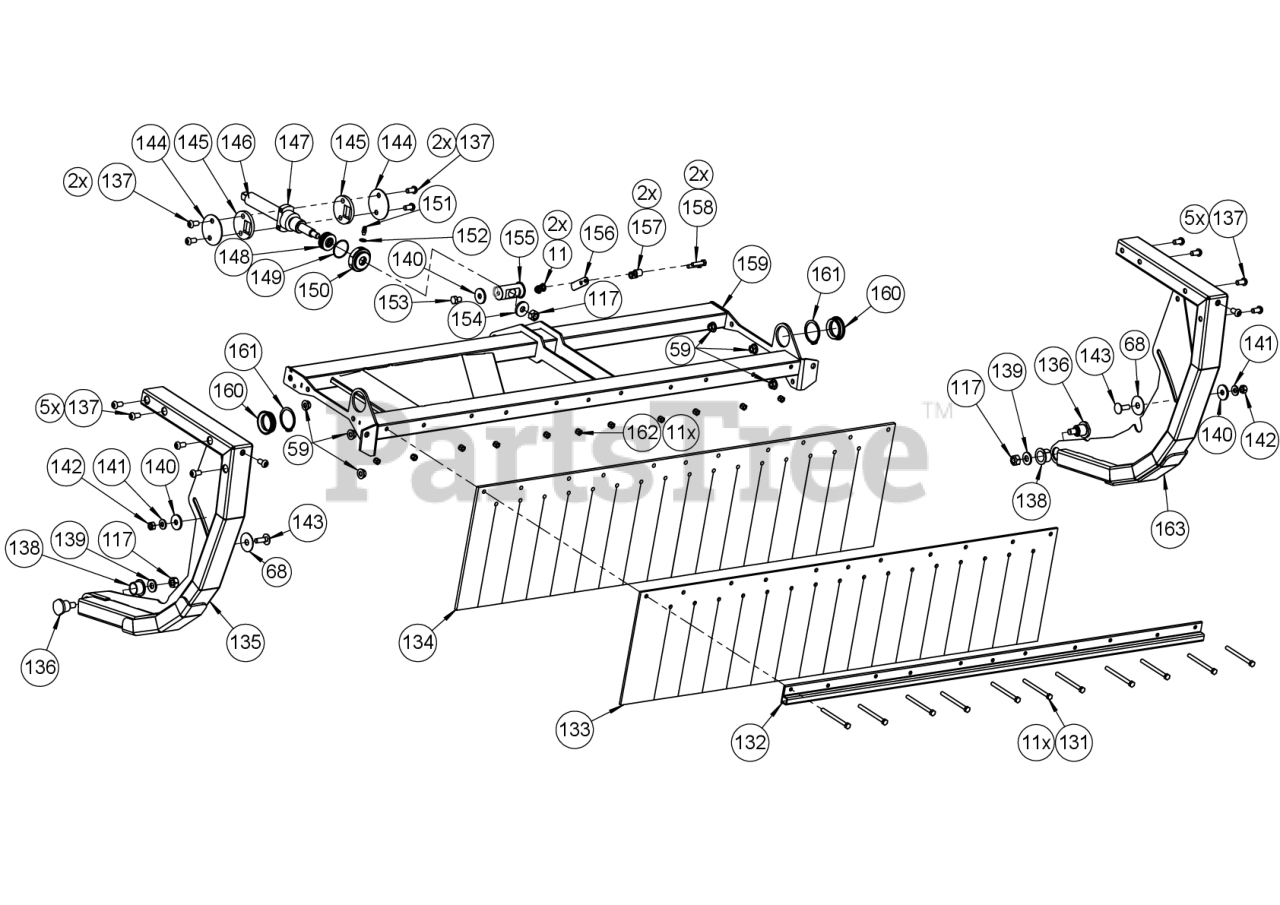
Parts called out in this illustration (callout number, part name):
11	NUT, FLG SLF LK M6 CL 8 ZCC
59	NUT, FLG SLF LK M8 CL 8 ZCC
68	WSHR, FLT M10.5 X M35 X M1.25
117	NUT, LK V-M10 DIN 980
131	BLT, HEX M6X75 DIN 931 8.8 ZCC
132	STRIP, SKIRT MOUNTING
133	SKIRT, BRUSH ENTRY (4MM)
134	SKIRT, BRUSH ENTRY (6MM)
135	ASSY, SKID (RH)
136	SCREW, COLLAR
137	TORX BHCS M8X16 8.8
138	BHSG, DU FLG BB201DU
139	WHSR, BLVL M10 DIN 6796
140	WSHR, FLT M9 X M28 X M3 ZCC
141	WSHR - BLVL M8 DIN 6796
142	NUT, HEX V-M8 DIN 980 8.8 ZCC
143	BLT, RHSN M8X25 DIN 603 8.8 ZCC
144	COVER, HOC BUSHING
145	BUSHING, HOC ADJ. NUT
146	SPINDLE, HOC ADJUSTING
147	NUT, ADJUSTING SPINDLE
148	BRG,BALL AXIAL-DP GROOVE-15X32X12
149	O - RING 32X1,5
150	HOUSING, BEARING/GREASE
151	FITTING, GREASE
152	WSHR, FLT M6 X M12 X M1 DIN 988
153	BLT, HEX M8X12 DIN 933 8.8 ZCC
154	WSHR, FLT M10.5 DIN 6340 ZCC
155	TRUNNION, HOC SPINDLE
156	PLATE, HOC SPRING
157	SPACER, SLEEVE
158	BLT, HEX M6X25 DIN 933 8.8 ZCC
159	FRAME, CUTTING ADJUSTMENT
161	RG-RTNG-EXT M38 DIN 471
162	NUT, HEX LK-NYL M6 DIN 982 8 ZCC
163	ASSY, SKID (LH)
